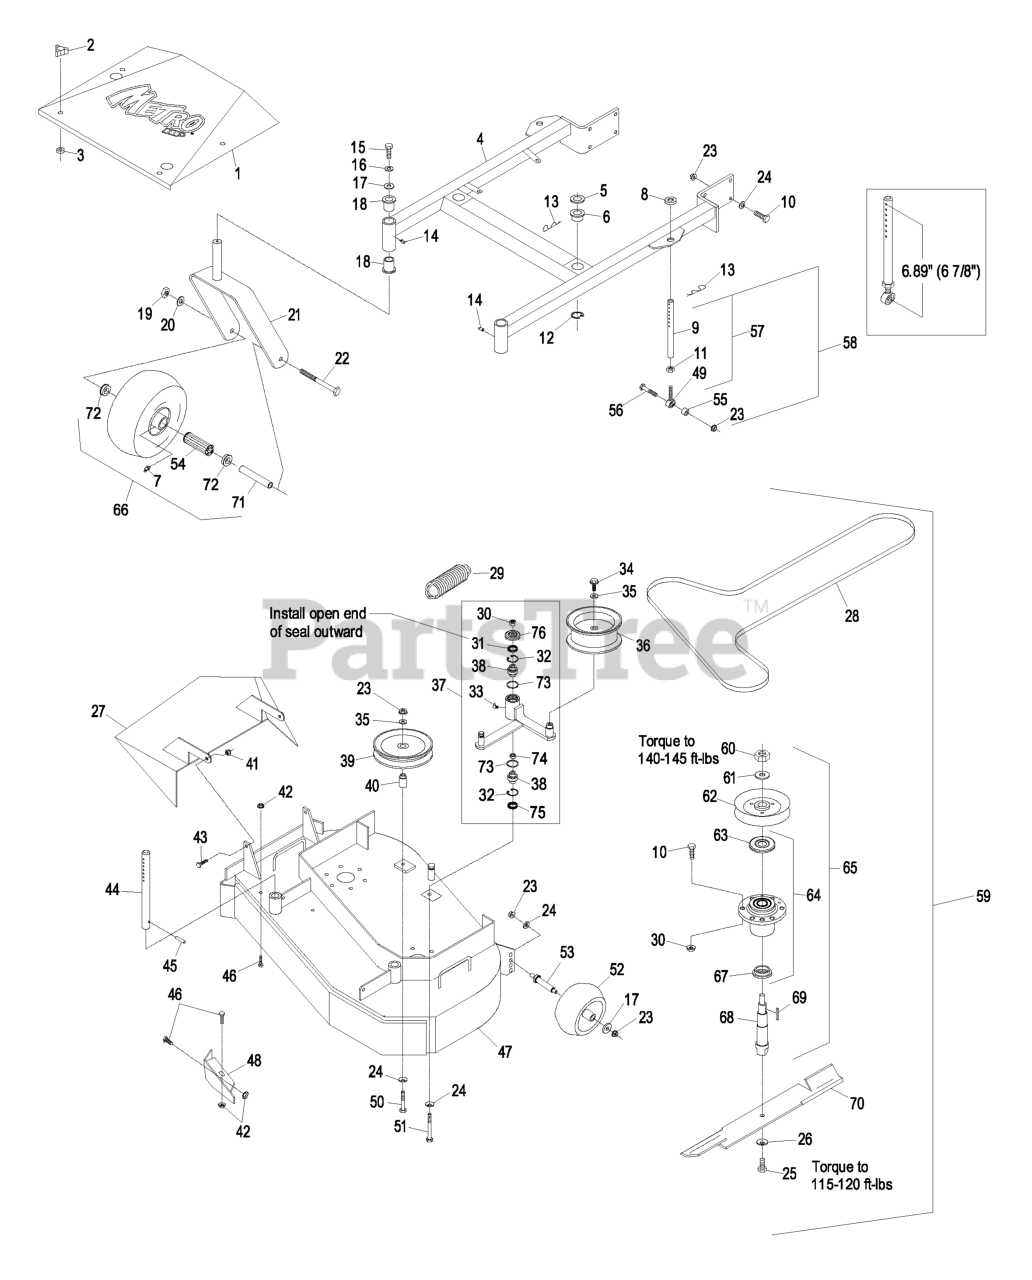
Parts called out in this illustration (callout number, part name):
1	SHIELD W/DECAL,MHP36
2	KNOB-3 PRONG
4	DECK SUPPORT W/BSHGS 36"
5	SPACER-DECK SUPPORT
6	BUSHING-DECK
7	FITTING-GREASE
9	LINK,SUPPORT
10	SCREW-HH
11	NUT-HEX
12	RING-RETAINING
13	PIN,HAIR COTTER
14	FITTING-GREASE
15	SCREW-HH
16	WASHER-LOCK
18	BEARING-FLANGED
19	NUT-HH
20	WASHER-LOCK
22	SCREW-HH
23	NUT-HHF, WHIZ
24	WASHER-BELLEVILLE
25	SCREW-CAP
26	WASHER-SPRING
27	WLD,DISCHARGE CHUTE 36/48
28	BELT,DECK DRIVE
30	NUT-LOCK, NI
31	SEAL-LIP, SINGLE
32	RING-SNAP
33	FITTING-GREASE, 90 DEG
34	SCREW-HHF
35	WASHER-FLAT
37	KIT, DECK IDLER TTHP 36"(
38	BEARING-SPHERICAL
39	PULLEY-IDLER
40	BUSHING-IDLER
41	NUT-LOCK, NI
43	SCREW-HH
44	ROD,DECK SUPPORT
46	SCREW-HH
47	ASM,DECK W/DECALS TTHP/MH
49	BALLJOINT
50	SCREW-HH
51	SCREW-HH
52	ROLLER-SCALP, ANTI
54	BEARING
56	SCREW-HH
59	Asm, Deck Complete
60	NUT-HH
62	SHEAVE,W/HUB 5.72
63	GUARD-BEARING, TOP
64	KIT, CUTTER HOUSING
65	ASM, CUTTER HSG
66	KIT, SP CASTER WHEEL REPL
67	SPACER-GUARD, BOTTOM
68	SPINDLE,SHAFT
69	KEY-RECTANGLE
72	BUSHING
75	SEAL-LIP, DOUBLE
76	GUARD-TOP
